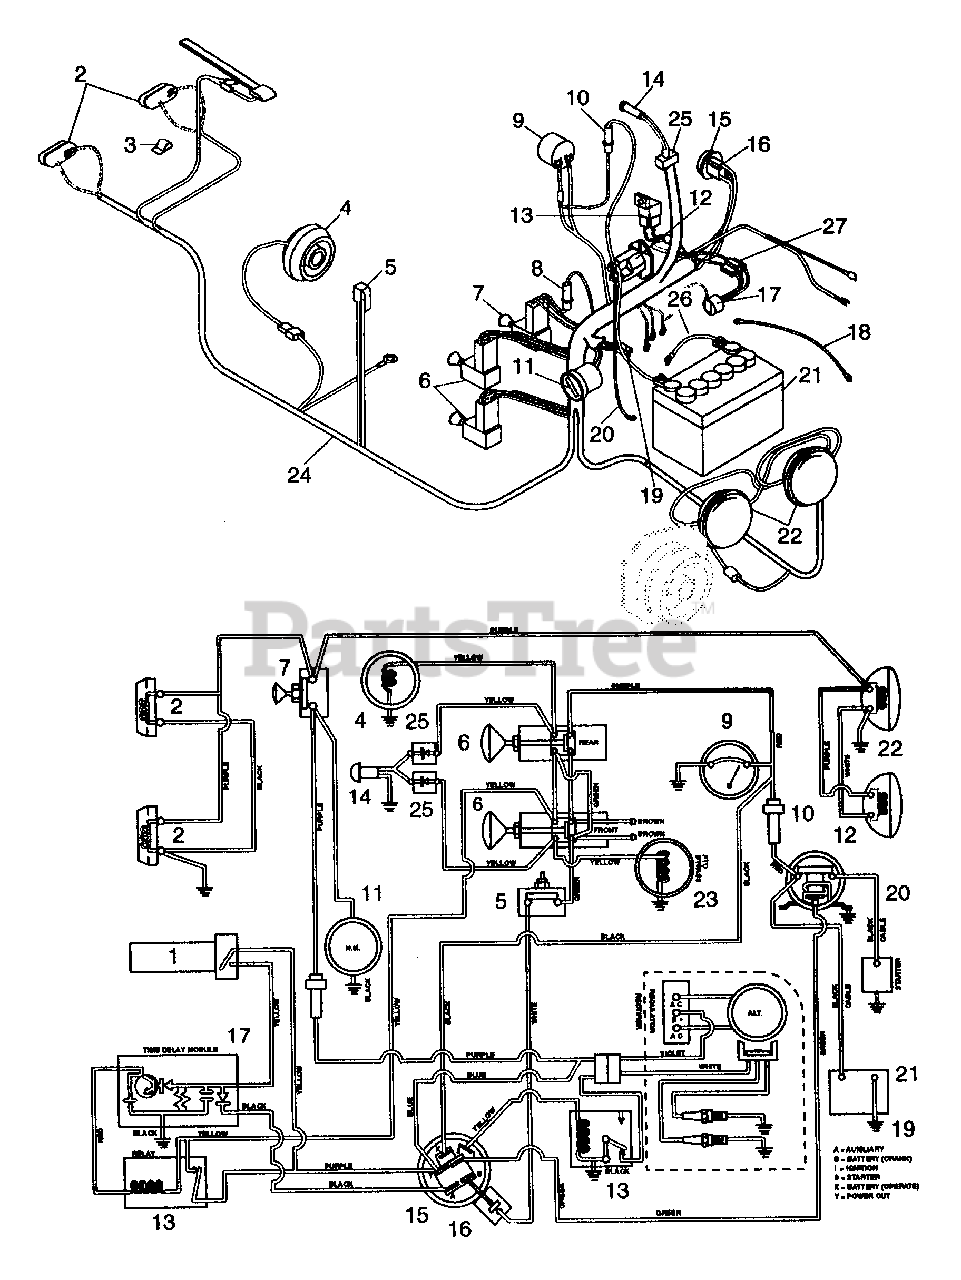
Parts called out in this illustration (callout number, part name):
1	SWITCH SEAT
2	TAIL LIGHT ASSEMBLY W/BULLET
2	TAIL LIGHT LENS
2	MALE DISCONNECT ADAPTER
2	SCR-MCH 10-24X.50 SLTR PL
2	WSHR-LK 10X.047 MED PL
2	NUT-HEX 10-24 PL
3	WIRE CLIP
4	ELECTRIC CLUTCH
5	SWITCH INTERLOCK
5	CONNECTOR
5	NUT-HEX .625-32 PL
6	CLUTCH SWITCH
6	CONNECTOR
6	WSHR-FL-STL .382X.812X.023 PL
7	LIGHT SWITCH
7	CONNECTOR
7	WSHR-FL-STL .382X.812X.023 PL
8	7 Amp Fuse
9	VOLTMETER
9	WSHR-LK-EXT #10 ID X .022
9	NUT 10-32 PL
10	30 Amp Fuse
11	HOUR METER
12	SOLENOID
12	WSHR-LK-EXT #10 ID X .022
12	NUT 10-32 PL
12	WSHR-LK-INT .313X.030 PL
12	NUT-JAM .312-24 PL
12	BLT-HEX .25-20X.75 PL GR2
12	BLT-HEX .25-20X1.00 GR2
12	WSHR-FL-STL.281X.62X.065 PL
12	WSHR-LK-EXT. 250 ID
13	RELAY
14	PTO INDICATOR LIGHT
14	LAMP SOCKET
14	SPEED NUT
15	SWITCH ASSEMBLY
15	CONNECTOR HOUSING
15	WSHR-LK-INT .563X.040 PL
15	NUT .562-24
16	DIODE ASSEMBLY
16	SCR-TAP .250-20X.50 HXSLHDPL
17	TIME DELAY MODULE
17	SCR-MCH 10-24X.50 SLTR PL
17	WSHR-LK 10X.047 MED PL
17	NUT-HEX 10-24 PL
18	GROUND CABLE .31X22.00X.31
19	GROUND CABLE .25X6.50X.31
19	WSHR-LK .250X.077 HVY PL
19	NUT-HEX .250-20 PL
20	STARTER CABLE .25X.35.25X.31
21	BATTERY
22	HEAD LIGHT
22	HEAD LIGHT RETAINER RING
22	SCR-MCH 10-24X.50 SLTR PL
22	WSHR-FL-STL .250X.562X.049 PL
23	CLUTCH ASSEMBLY 1 1/8 BORE
23	CLUTCH ASSEMBLY 1-1/4 BORE
24	WIRING HARNESS
25	MOLDED DIODE PLUG 1 AMP
26	STARTER CABLE 6.75"
27	CONNECTOR
